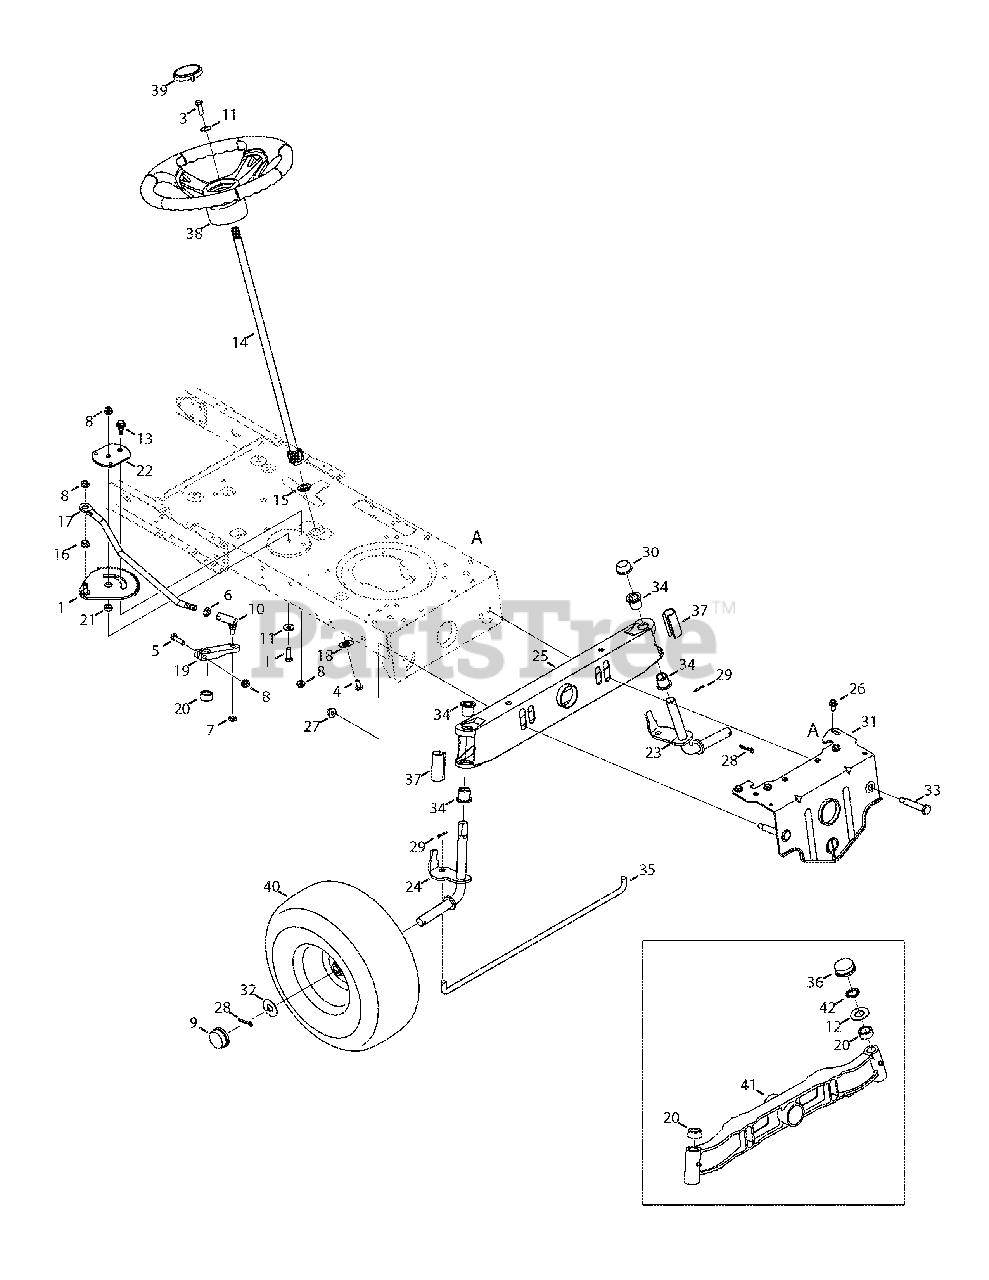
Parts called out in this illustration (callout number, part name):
1	Gear Assembly, Steering
2	Screw, 5/16-18, 1.00, Gr5
3	Screw, 5/16-18, 1.00, Gr5, Lock
4	Screw, Mach, 5/16-18, 0.750
5	Screw, 5/16-18, 1.75, Gr5
6	Nut, Jam, 7/16-20, Gr2
7	Nut, Jam Lock, 3/8-24, Gr2
8	Nut, Flange Lock, 5/16-18, Grf
9	Hub Cap
10	Ball Joint, 7/16-20, Lock
11	Washer, Bell, .340 x .872 x .060
12	Washer, Flat, .78 x 1.59 x .60
13	Shoulder Screw, .435 x .3485, 5/16-18
14	Steering Shaft, 5/8 Spline x 21.86
15	Bearing, Flange, Hex 5/8
16	Plastic Bushing .380 ID
17	Drag Link, Steering
18	Cap, 1.25 x .16
20	Spacer, .710 ID x .125 OD x .56
21	Spacer, .322 ID x .625 OD x .21
22	Stabilizer Plate, Gear Segment
23	Axle Assembly, LH (38" & 42" Deck)
24	Axle Assembly, RH (38" & 42" Deck)
25	Pivot Bar, Cast Iron
26	Screw, 5/16-18, 0.750
27	Nut, Flange Lock, 3/8-16, GrF
28	Pin, Cotter, 5/32, 1.25
29	Pin, Cotter, 1/8 x 0.75
30	Push Cap, 3/4
32	Washer, Flat, .78 x 1.59 x .060
33	Scr., Shlder, .500 x 2.380, 3/8-16
34	Bearing, Flange, .760 x .941 x 1.0
35	Tie Rod
36	Push Cap
37	Axle End Cap, Standard
38	Steering Wheel, Standard Grip
39	Cap, Steering Wheel (no logo)
41	Pivot Bar, Cast
42	Push Nut 3/4 Dia.
